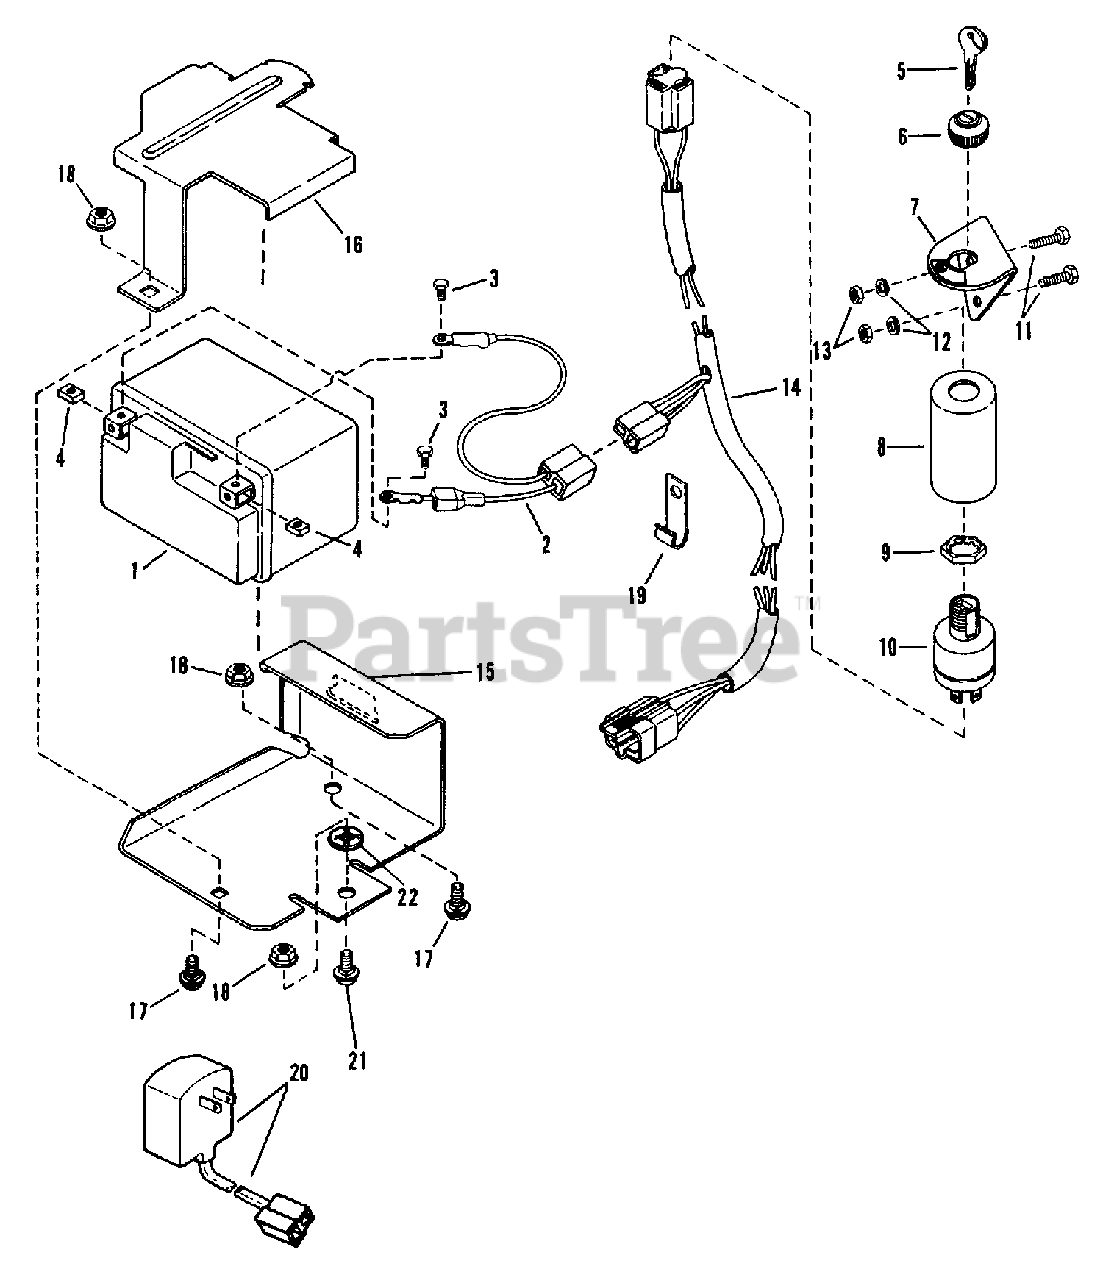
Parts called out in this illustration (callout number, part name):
1	KIT, Battery, 12 Volt, 35 CCA (Includes 1, 2, 3, & 4)
2	HARNESS, Battery
3	SCREW, #10-24 x 1/2 Hex Head Cap
4	NUT, #10-24 Square
5	KEY, (Set of 2)
6	ASSEMBLY, Seal & Face Nut
7	BRACKET, Ignition Switch
8	COVER, Switch
9	NUT, 3/4-20 Lock
10	SWITCH, Ignition
11	SCREW, 1/4-28 x 1 3/8" Hex Head Cap
12	WASHER, 1/4 Internal Tooth Lock
13	NUT, 1/4-28 Hex
14	HARNESS, Wiring 60"
15	BRACKET, Battery
16	COVER, Battery
17	BOLT, 5/16-18 x 1/2" Carriage
18	NUT, 5/16-18 Hex Flange Lock
19	CLIP, Wiring
20	CHARGER, Battery (60 Hertz)
21	BOLT, 5/16-18 x 5/8" Short Neck. Carriage, Gr. 5
22	RETAINER, 5/16" Bolt
